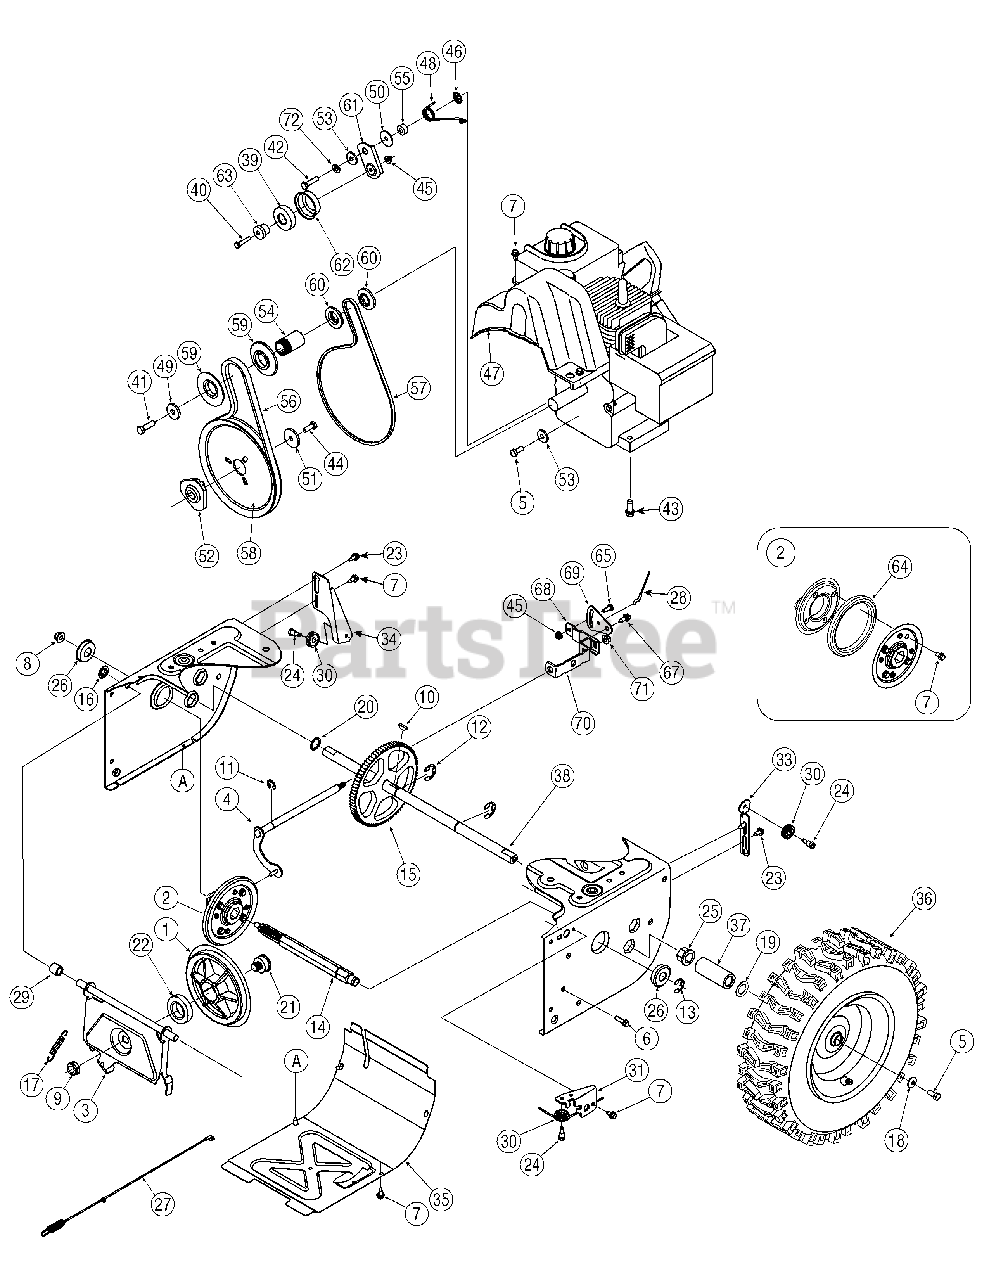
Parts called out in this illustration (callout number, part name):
1	Disc, Friction Wheel
2	Friction Wheel Assembly, 5.5 OD
4	Shift Assembly, Rod
5	Hex Screw, 5/16-24, .750, Gr5
6	Screw, 1/4-20, 1.000
7	Screw, 1/4-14 x .625
8	Nut, Flange Lock, 3/8-16, Nylon
9	Nut, Jam Lock, 5/8-18, Gr5, Nylon
10	Key, Hi Pro, 3/16 x 3/4 Dia
11	E-ring, .500 Dia.
12	E-ring, Retaining, .875 Dia.
13	E-ring, .750 Dia.
14	Hex Shaft, .8125, 7-Tooth
15	Gear, 80-Tooth
16	Speed Nut, .500
17	Extension Spring
18	Washer, Bell, .340 x .872 x.060
19	Washer, Flat, .793 x 1.24 x.060
20	Washer, Flat, .75 x 1.00 x .060
21	Pin, Friction Disc
22	Ball Bearing, 30 x 55 x13
23	Screw, Shoulder, .37 x .105, 1/4-20
24	Screw, 1/4-28, .375
25	Bearing, Hex Flange x .75 ID
26	Bearing, Ball, 17 x 40 x12
27	Clutch Cable, Wheel, 44.95"
28	Clutch Cable, Auger, 47.23"
29	Spacer, .508 ID x .75 OD x.68
30	Roller, Cable
36	Valve Only
37	Spacer, 1.25 x .75 x 3.0
38	Axle, .75 x 22"
39	Ball Bearing
40	Hex Screw, 1/4-20, 1.25, Gr5
41	Hex Screw, 3/8-24, 1.25,
42	Hex Screw, 5/16-24, 1.25,
43	Screw, Sems, 3/8-16, 1.00
44	Hex Screw, 5/16-24, .875, GR8
45	Nut, Flange Lock, 1/4-20, Nylon
46	Nut, Push-on, .25 Dia.
47	Cover, Belt
48	Spring, Torsion, .850 ID x.354
49	Washer, Flat, .406 x 1.25 x .157
50	Washer, Flat, .330 x 1.25 x .06
51	Washer, Flat, .34 x 1.50 x .150
52	Pulley, Adapter, .75 Dia.
53	Spacer, Shoulder
54	Spacer, .875 ID x 1.185 OD
55	Spacer, .340 x .750 x .360
56	Belt, Auger Drive 1/2"
57	Belt, Wheel Drive 3/8"
58	Pulley, Auger Drive, 8.1 x .5
59	Pulley, Half, 2.6 OD
60	Pulley, Half, 1.5 OD
61	Idler Bracket, Wheel Drive
62	Sleeve, Bearing Idler
63	Spacer, Shoulder, .26 x .79 x.538
64	Rubber, Friction Wheel, 5.5 OD
65	Hex Screw, 1/4-20, .620, Gr5
67	Screw, Shoulder, .37 x .105, 1/4-20
68	Bracket, Shift Spacer
71	Nut, Flange Lock, 5/16-18, Nylon
72	Washer, Lock, 5/16
